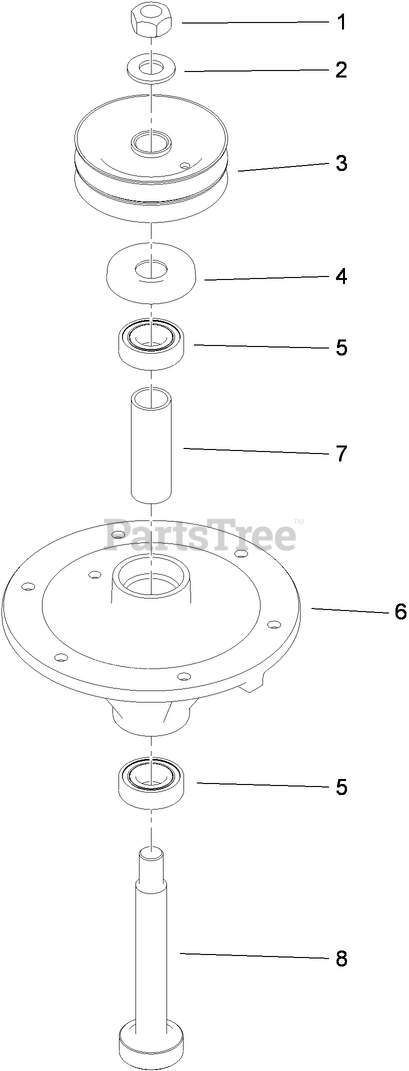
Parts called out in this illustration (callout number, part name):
1	NUT-HEX
2	WASHER
3	PULLEY ASM
4	SHIELD-BEARING
5	BEARING-BALL
6	HOUSING-SPINDLE
7	SPACER-BEARING
8	SHAFT-SPINDLE
